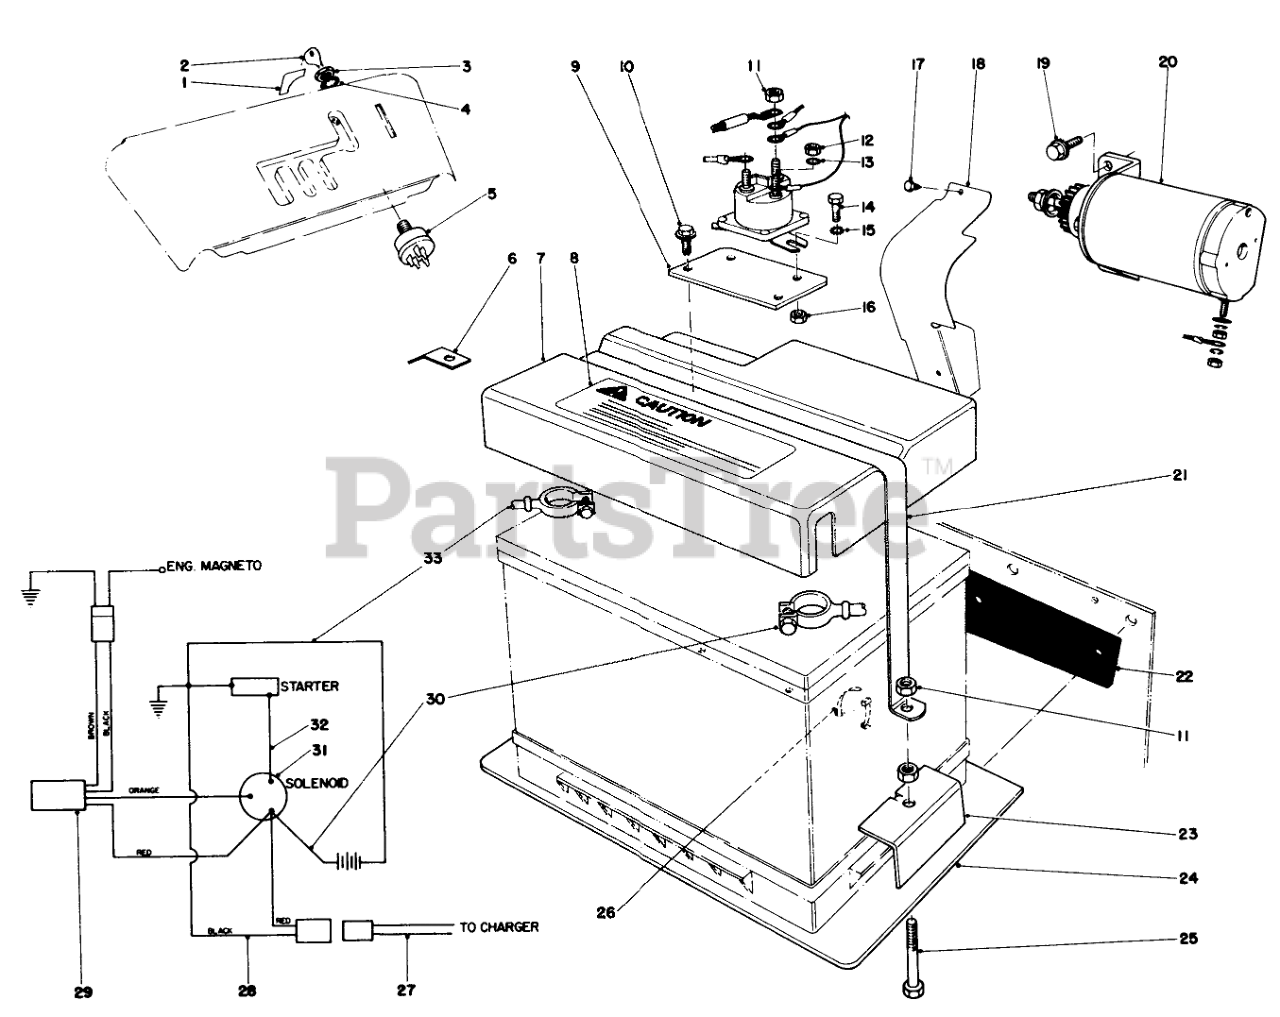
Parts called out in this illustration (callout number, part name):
1	Decal Switch
2	Key
3	NUT-HH
4	WASHER-TOOTH, INTERNAL
5	SWITCH-STARTER
6	Bracken Wire Clamp
7	Battery Cover (Incl. Ref. #8)
8	Decal-Caution
9	Bracket Solenoid
10	SCREW-HWH
11	NUT-HEX
12	NUT-HEX
13	WASHER-LOCK, INT
14	SCREW-HH
15	SCREW-HH
16	NUT-LOCK, NI
17	Hex Hd. Sems Screw
18	Pinion Shield
19	Screw-HH
20	Starter Motor & Pinion Assy.
21	Strap Battery
22	Batery Isolation Pad
23	BATTERY CLAMP
24	Battery Mounting Plate
25	SCREW-HH
26	TIE-CABLE
27	MALE WIRE ASM
28	FEMALE WIRE ASM
29	12 V IGN WIRE HARNESS
30	BATT-SOLENOID CABLE
31	SOLENOID
32	STRT MTR-SOLNOID WIRE
33	BATT-GROUND CABLE
